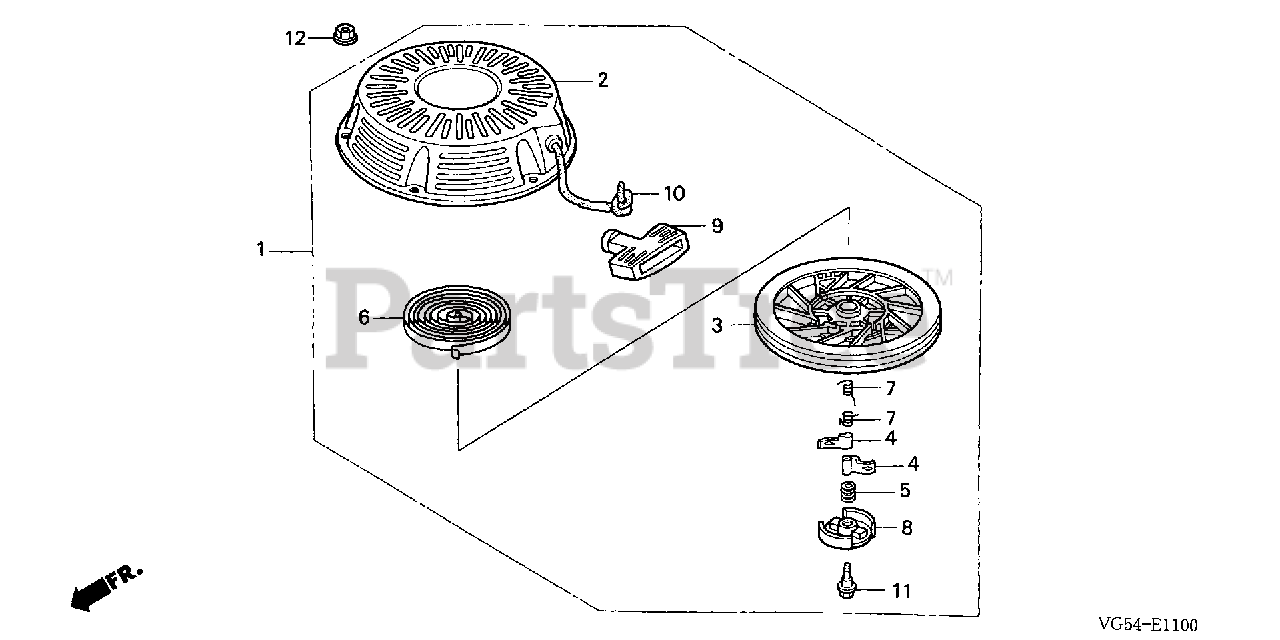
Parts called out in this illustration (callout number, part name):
1	STARTER ASSY., RECOIL *R8* (BRIGHT RED)
1	STARTER ASSY., RECOIL *R280* (POWER RED)
2	CASE, RECOIL STARTER *R8* (BRIGHT RED)
2	CASE, RECOIL STARTER *R280* (POWER RED)
3	PULLEY, RECOIL STARTER
4	RATCHET, STARTER
5	SPRING, FRICTION
6	SPRING, STARTER RETURN
7	SPRING, RATCHET
8	RETAINER, SPRING
9	GRIP, STARTER
10	ROPE, RECOIL STARTER (#6X64") (N/A: USE P/N 08560-ZG921-11)
11	SCREW, CENTER
12	NUT, FLANGE (6MM)
